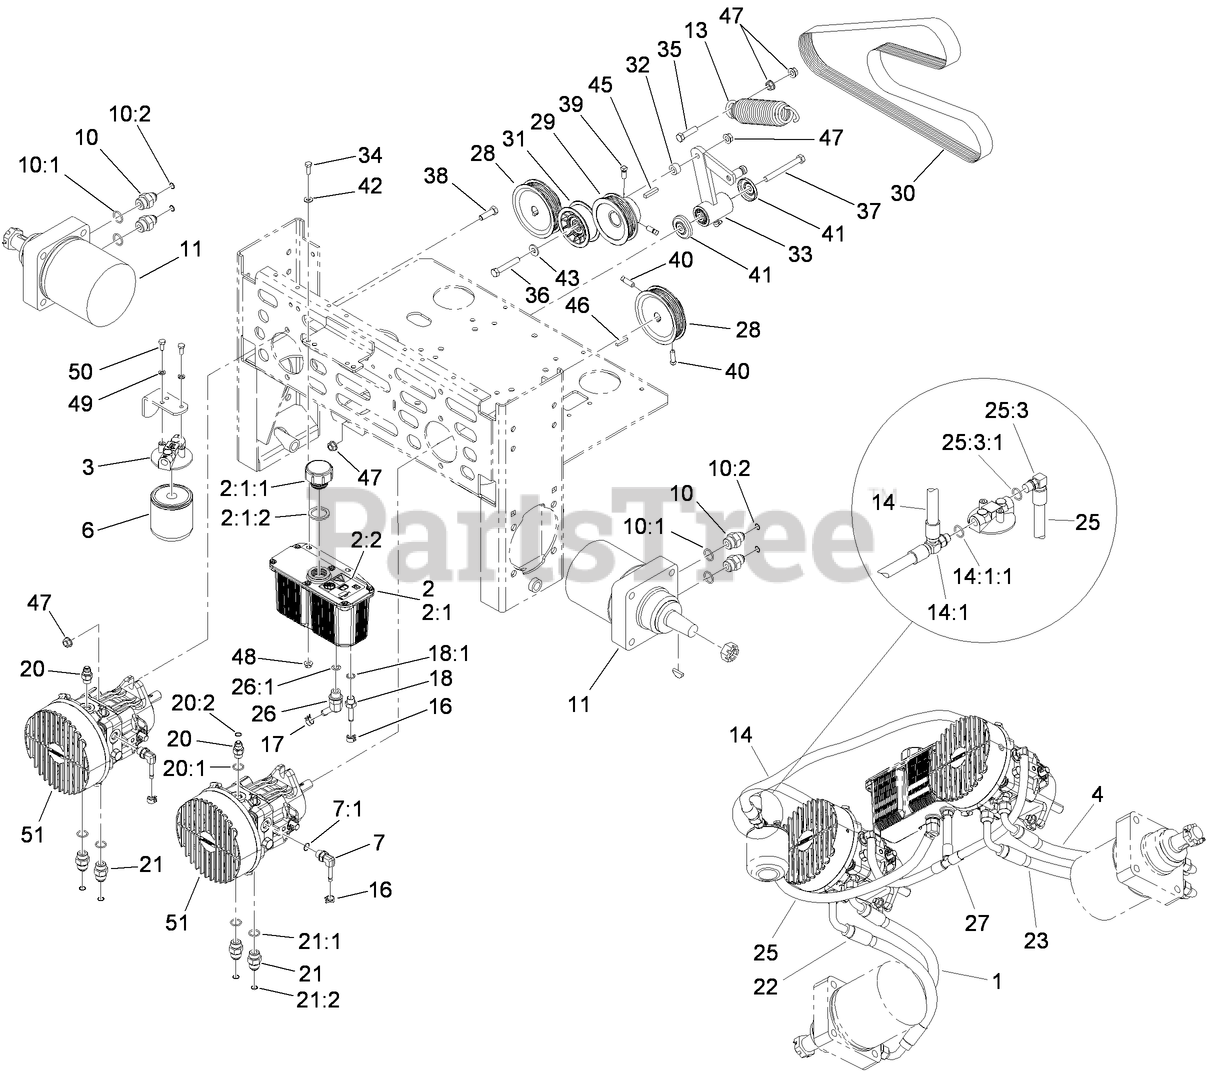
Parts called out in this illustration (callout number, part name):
1	HYD HOSE ASM
2	HYD RESERVOIR ASM
2:1	Reservoir-HYD
2:1:1	CAP-RESERVOIR, HYD
2:1:2	GASKET-CAP
2:2	DECAL-WARNING
3	HEAD-FILTER
4	HYD HOSE ASM
6	FILTER-OIL, HYD
6	FILTER-OIL, HYD (WINTER)
7	ELBOW-90 DEG
7:1	O-RING
10	Fitting-Straight
10:1	O-RING
10:2	O-Ring
11	MOTOR-WHEEL
13	EXTENSION-SPRING
14	HYD HOSE ASM
14:1	ADAPTER-RUN, TEE
14:1:1	O-RING
16	Clamp-Hose
17	Clamp-Hose
18	Adapter-Straight
18:1	O-RING
20	FITTING-STRAIGHT
20:1	O-Ring
20:2	O-RING
21	FITTING-STRAIGHT
21:1	O-RING
21:2	O-Ring
22	HYD HOSE ASM
23	HYD HOSE ASM
25	HYD HOSE ASM
25:3	FITTING-BARBED, 90 DEG
25:3:1	O-RING
26	FITTING-BARBED, 45 DEG
26:1	O-RING
27	HYD Hose ASM
28	SHEAVE
29	SHEAVE
31	PULLEY-FLAT IDLER
32	SPACER
33	PUMP IDLER ASM
34	SCREW-HH
35	SCREW-HH
36	SCREW-HH
37	SCREW-HH
38	SCREW-HH
39	SCREW-SET
40	SCREW-SET
41	GUARD-TOP
42	WASHER-FLAT
43	WASHER-FLAT
45	KEY-SQUARE
46	KEY-SQUARE
47	NUT-HHF, WHIZ
48	NUT-HF
49	WASHER-LOCK
50	SCREW-HH
51	PUMP-HYD
